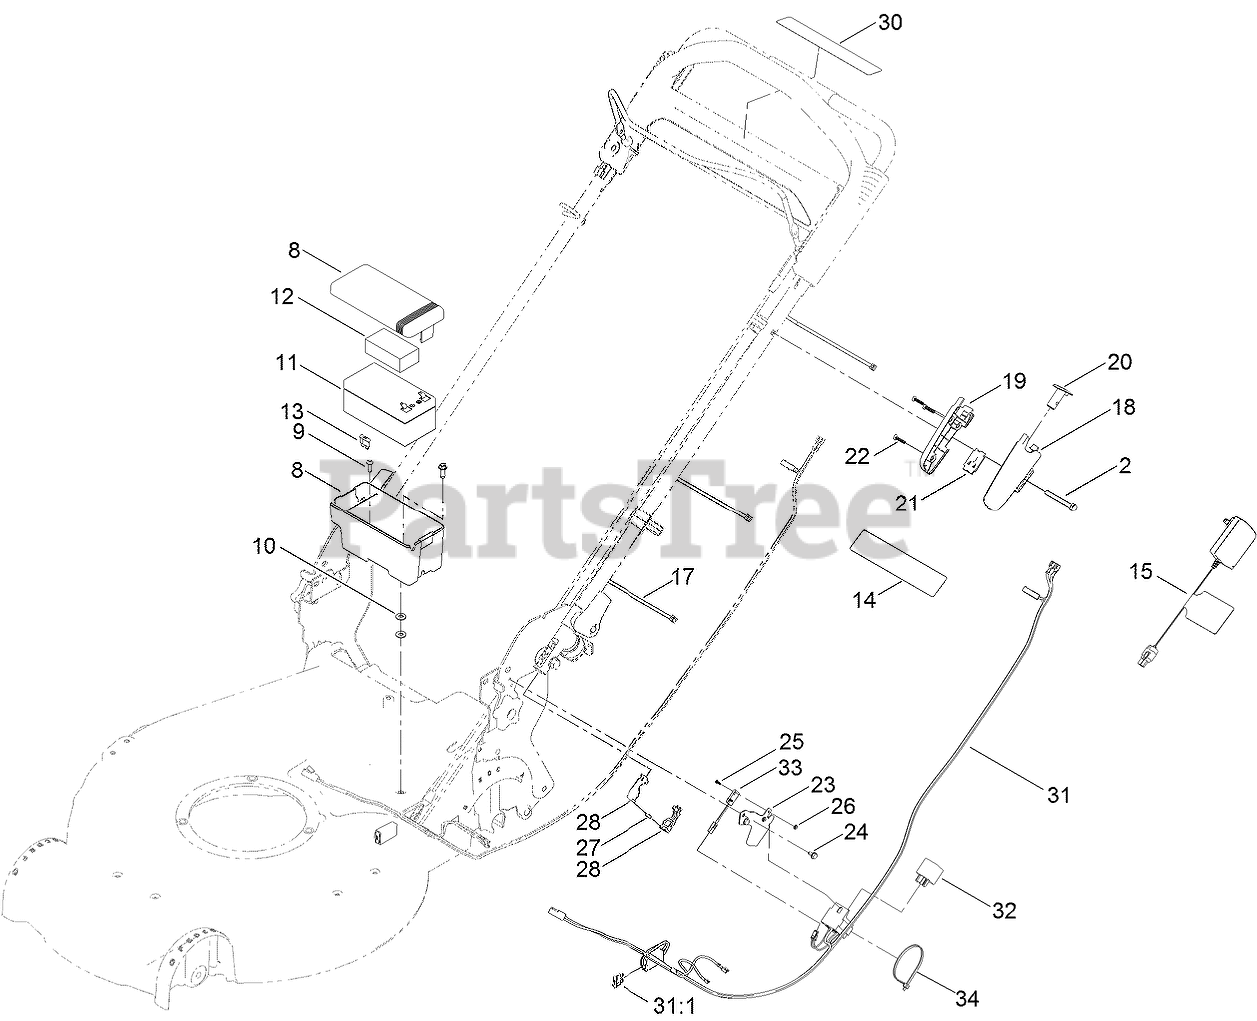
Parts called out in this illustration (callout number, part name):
2	SCREW-HH
8	BATTERY BOX ASM
10	WASHER-FLAT
11	BATTERY-WET
12	FOAM-BATTERY, TOP
13	FUSE-40 AMP
14	DECAL-WARNING
15	CHARGER, BATTERY (12V)
17	TIE-CABLE
18	HOUSING-SWITCH, LH
19	HOUSING-SWITCH, RH
20	BUTTON-SWITCH
21	SWITCH-PUSH BUTTON
22	SCREW-PPH
23	BRACKET-SENSOR
24	SCREW-HWH
26	NUT-LOCK, NI
27	MAGNET
28	HOUSING-MAGNET
30	DECAL-BUTTON, PUSH
31	HARNESS-WIRE
31:1	FUSE-40 AMP
33	REED SWITCH ASM
34	TIE-CABLE
